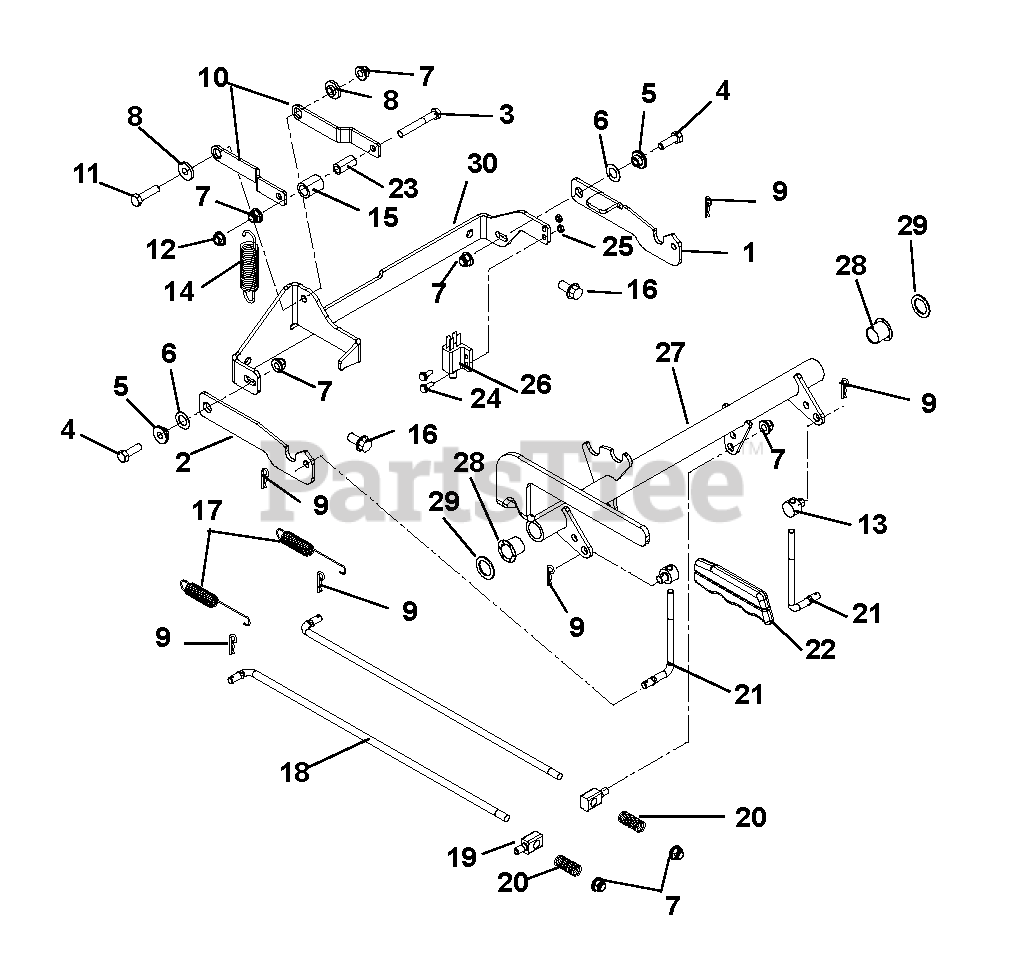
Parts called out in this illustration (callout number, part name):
1	Link, Brake Interlock
2	Interlock, Brake
3	Bolt, Hex .31-18 x 2.25 Grade 5
4	Bolt, Hex .31-18 x 1.00 Grade 5
5	Bushing, Flange .312 x .500 x .344 x .880
6	Washer, Flat Steel .505 x .875 x .024
7	Nut, Flange Nyloc 5/16-18
8	Shoulder Spacer
9	Pin, Hair Internal .08 x .18 x 1.18
10	Arm, Brake Cam
11	Bolt, Hex .31-18 x 1.25 Grade 5
12	Nut, Locking Top Flange .31-18
13	Trunnion, Brake
14	Spring, Tension .105 x .812 x 3.88
15	Roller, Cam Lock
16	Screw, Tapping .38-16 x .75 Hex Washer Head
17	Spring, Tension .056 x .60 x 4.40
18	Rod, Park Brake
19	Pin, Pivot
20	Spring, Compression
21	Link, Interlock Brake
22	Grip, Park Brake
24	Screw, Machine 10-24 x .50 Hex Washer Head
25	Nut, Locking Nylon 10-24 with Insert
26	Switch, Double Pole
27	Weldment, Brake Shaft
28	Bushing, IGLIDE Clip
29	Washer, Flat Steel .754 x 1.125 x .062
30	Bracket, Brake Mounting
